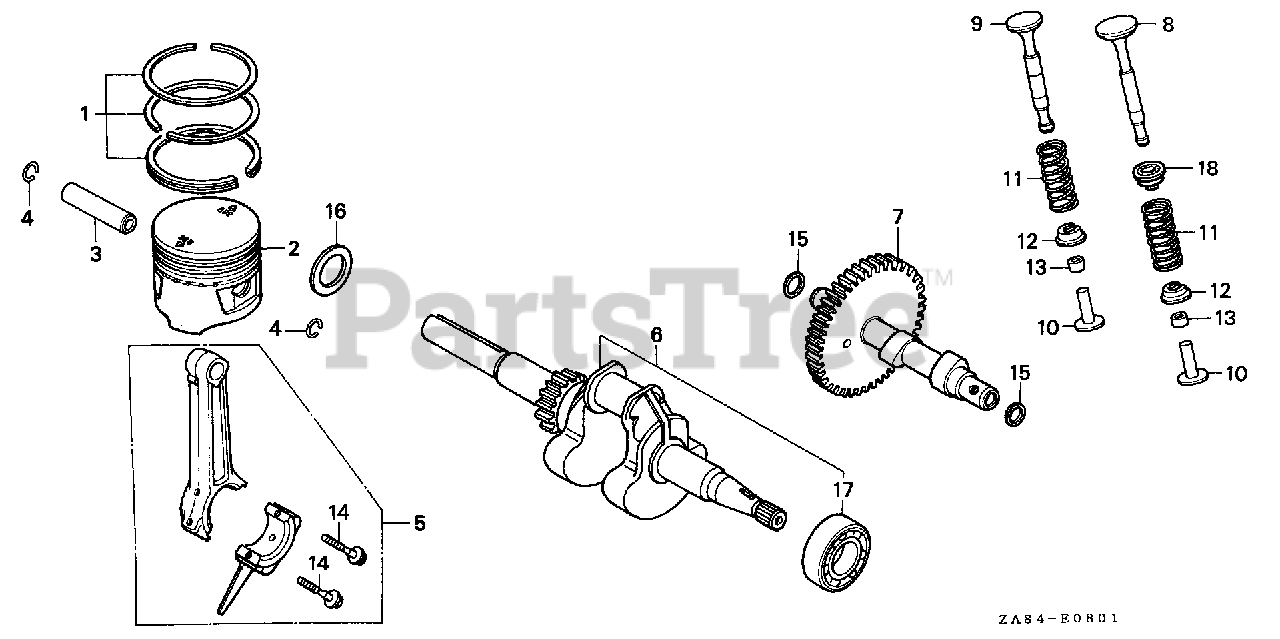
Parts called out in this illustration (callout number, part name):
1	RING SET, PISTON (STD)
1	RING SET, PISTON (OS 0.25)
1	RING SET, PISTON (OS 0.50)
1	RING SET, PISTON (0.75)
2	PISTON (STD)
2	PISTON (OS 0.25)
2	PISTON (OS 0.50)
2	PISTON (0.75)
3	PIN, PISTON
4	CLIP, PISTON PIN (10MM)
5	ROD ASSY., CONNECTING (STD)
5	ROD ASSY., CONNECTING (US)
6	CRANKSHAFT
7	CAMSHAFT
8	VALVE, IN.
9	VALVE, EX.
10	LIFTER, VALVE
11	SPRING, VALVE
12	RETAINER, VALVE SPRING
13	ADJUSTER, TAPPET CLEARANCE
14	BOLT, CONNECTING ROD
15	WASHER (12MM)
16	WASHER, THRUST (20X1.00)
17	BEARING, RADIAL BALL (6203)
